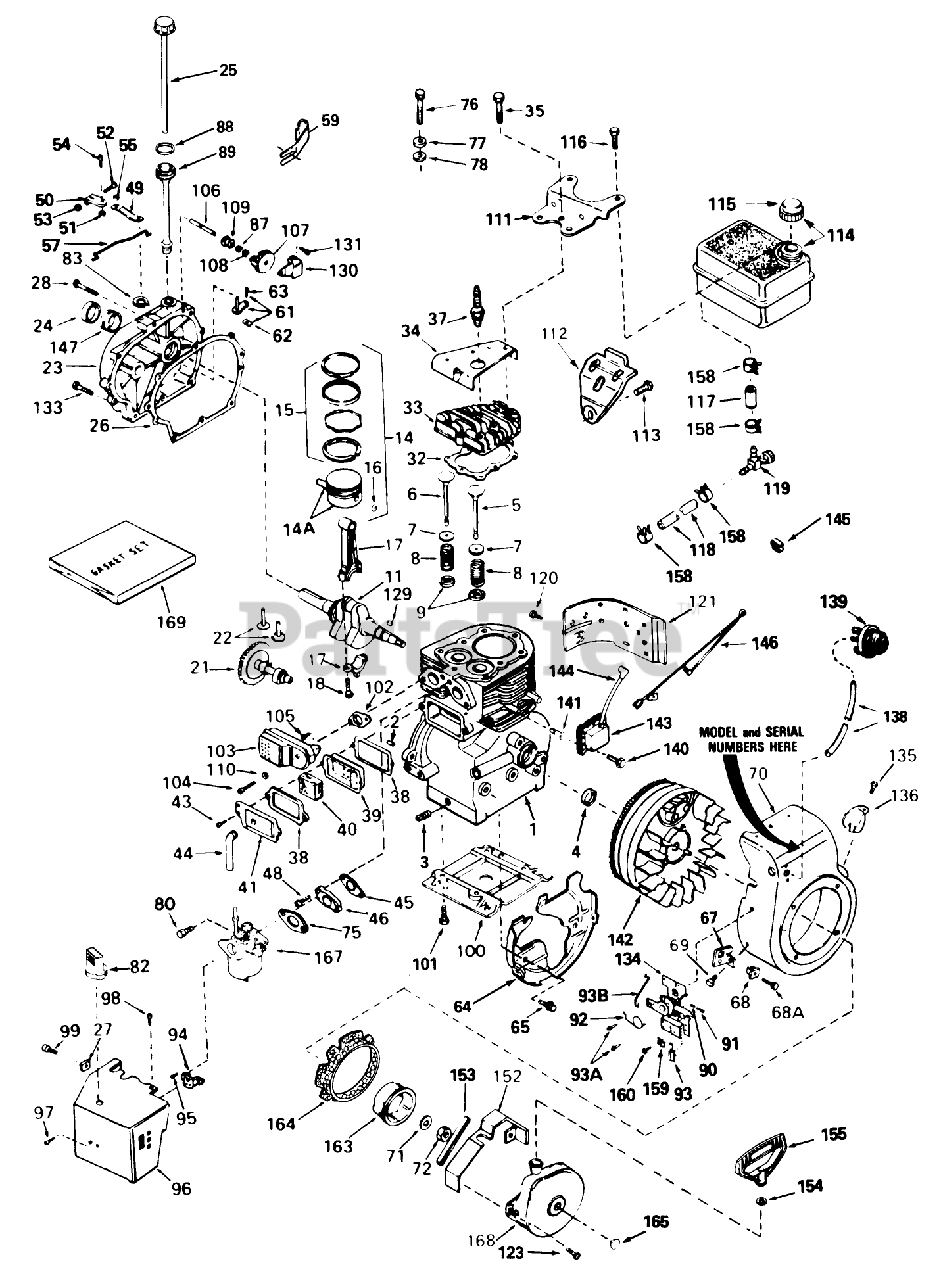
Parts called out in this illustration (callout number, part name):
1	Cylinder Assy. (Incl. Ref. #2, 3 4)
2	Pin-Dowel
3	Plug-Drain, Oil (SQH 1/4-18)
4	Oil Seal
5	Valve, Intake (Standard)(Incl. No. 9)
5	Valve, Intake (1/32" oversize)(Incl. No. 9)
6	Valve, Exhaust (Standard)(Incl. No. 9)
6	Valve, Exhaust (1/32" oversize)(Incl. No. 9)
7	Cap-Spring, Valve
8	Spring-Valve
9	Keeper-Spring, Valve
11	Crankshaft Assy. (Incl. Ref. #12 13)
14	Piston, Pin Ring Assy. (Std.)(Incl. Ref. #14A, 15 16)
14	Piston, Pin Ring Assy. (.010 Oversize)(Incl. Ref. #14A, 15 16)
14	Piston, Pin Ring Assy. (.020 Oversize)(Incl. Ref. #14A,15 16)
14A	Piston Pin Assy. (Std.)(Incl. Ref. #16)
14A	Piston Pin Assy. (.010 Oversize)(Incl. Ref. #16)
14A	Piston Pin Assy. (.020 Oversize)(Incl. Ref. #16)
15	Ring Set (Std.)
15	Ring Set (.020" OS)
15	Ring Set (.010" OS)
17	Rod Assy., Connecting (Incl. Ref. #18)
18	Bolt-Connecting Rod
21	Camshaft
22	Lifter-Valve
23	Cover, Cylinder (Incl. Nos. 24 106)
24	Oil Seal
25	Dipstick
26	Gasket-Cover, Cylinder
27	Nut-U Type
28	Screw (1/4-20 x 1-1/4)
32	Gasket-Head, Cylinder
33	CYLINDER HEAD
34	Cover-Head, Cylinder
35	Screw (5/16-18 X 2-1/2)
37	Spark Plug-Resistor (R J19 L M)
38	Gasket-Breather
39	Body-Breather
40	Element-Breather
41	Cover-Valve
43	Screw
44	Tube-Breather
45	Gasket-Intake
46	481-1279 SENATOR RO
48	Screw
49	Lever-Governor
50	Clamp-Lever, Governor
51	Nut-Lock
52	Screw
53	Nut-Lock
54	Screw
55	Washer-Lock
57	Governor Link
59	Clip-Tube, Fill
61	Rod, Governor (Incl. Nos.62 63)
62	Yoke-Governor
63	Screw (6-40x5/16)
64	Baffle-Blower Housing
65	Screw (1/4-20x19/32)
67	Bracket
68	Grommet
68A	Screw
69	Screw
70	Housing, Blower (Incl. Ref. #135 136)
71	Washer-Belleville
72	Flywheel Nut
75	Gasket-Carburetor
76	Screw (5/16-18 X 2-1/2)
77	Washer-Belleville
78	Washer-Flat
80	Screw-Hex Hd.
82	Knob-Choke
83	Ring-Retaining
87	Washer-Flat
88	O-Ring
89	Tube-Fill, Oil
90	Spring-Compression
91	Screw
92	Spring-Throttle
93	Terminal
93A	Screw (10-32 x 1/2)
93B	Link-Throttle
94	Bracket-Choke
95	Screw (10-32 x 1/2)
96	Carburetor Cover
97	Screw (8-32 X 5/16)
98	Screw (10-32x1/2)
99	Screw (8-32 x 3/8)
100	Base Engine
101	Screw
102	Gasket Exhaust
103	Muffler
104	Screw (5/16-18 X 2)
105	Screw
106	Shaft-Governor
107	Governor Gear ASM
108	Ring-Retaining
109	Spool-Governor
110	Washer
111	Plate, Fuel Tank Mounting
112	Bracket, Fuel Tank Mounting
113	Screw (1/4-20x19/32)
114	481-1261 SENATOR TI
115	Cap, Fuel
116	Screw (1/4-15x7/8)
117	Line-Fuel
118	Line-Fuel (8.62)
119	Valve-Shut Off
120	Screw
121	Extension-Blower Hsng.
123	Screw
129	Key-Flywheel
130	Bracket, Governor
131	Screw (10-24x1/2)
133	Screw
134	Control Assy., Remote Speed (Incl. Ref. #90 thru 93)
135	Screw (8-32 x 3/8)
136	Screw
138	Line-Primer
139	Primer-Asm
140	Screw
142	Flywheel
143	Solid State
144	Cover-Spark Plug
145	Clip-Wire
146	Ground Wire
147	Bushing-Crankshaft
152	Guard-Starter
153	Seal, Snowguard
154	Washer
155	Handle-Starter, Mitten Grip
158	Clamp-Line, Fuel
159	Conduit
160	Screw (10-32 x 3/8)
163	Cup-Starter
164	Screen-Starter
165	Plug-Starter
167	Carburetor (Incl. Ref. #75)
168	Starter-Rewind
169	Gasket Set (Incl. Items Marked *)
